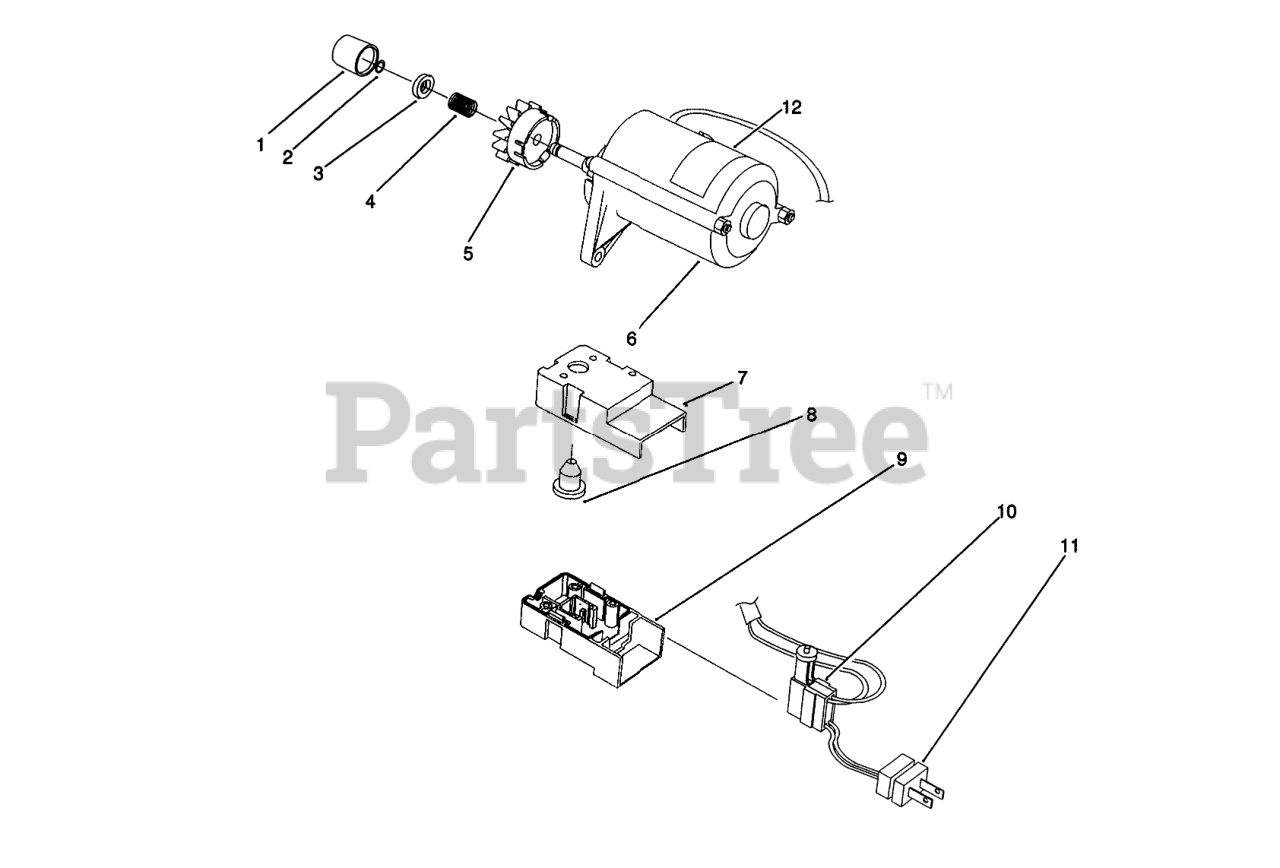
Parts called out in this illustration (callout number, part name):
1	CAP-PINION
2	RING-LOCK
3	PINION STOP
4	SPRING
5	Pinion Assembly
6	Starter Motor Assembly
7	Cap-Switch Housing
8	BOOT-SWITCH
9	OBS BASE X
10	SWITCH-STARTER
11	Plug
12	Decal-UL
